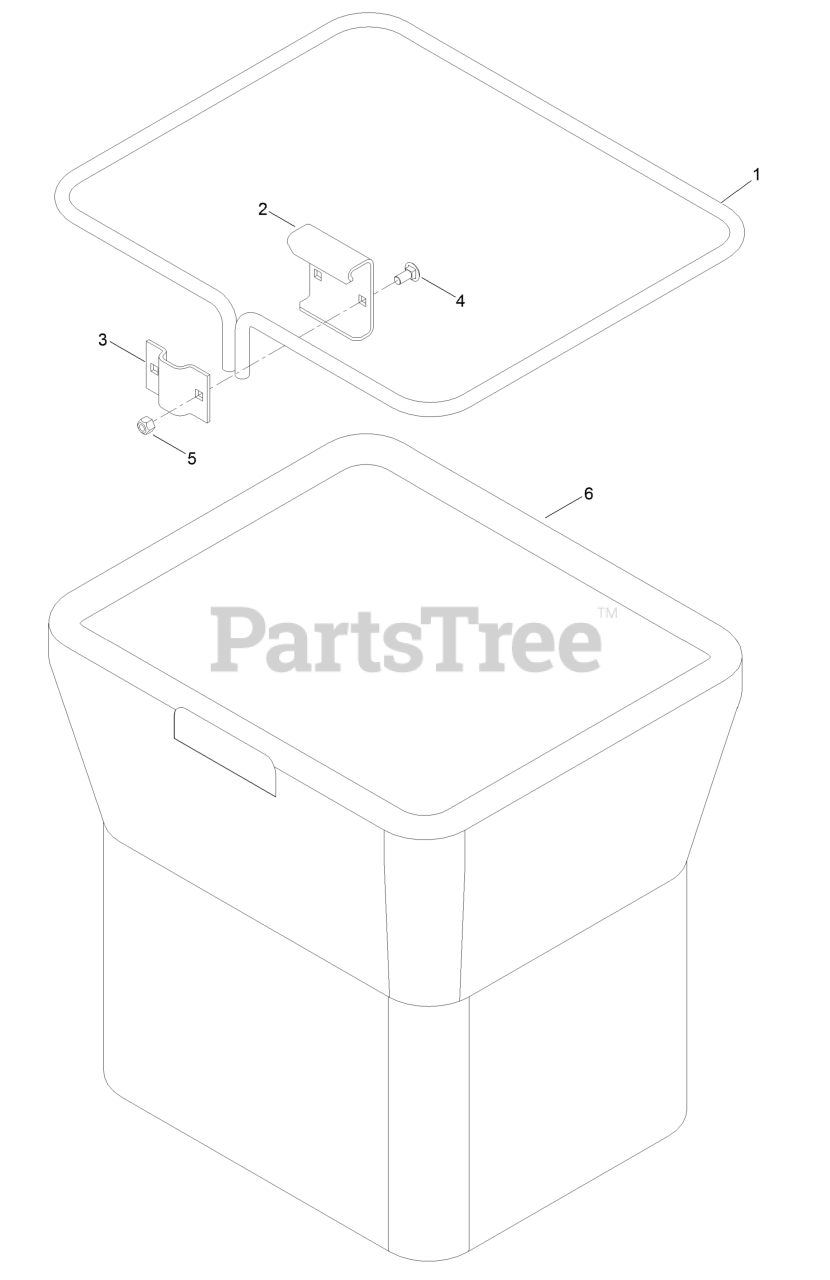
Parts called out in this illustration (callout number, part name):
1	FRAME-BAG
2	HANGER-BAG
4	BOLT-CARR
5	NUT-LOCK, NI
6	BAG
